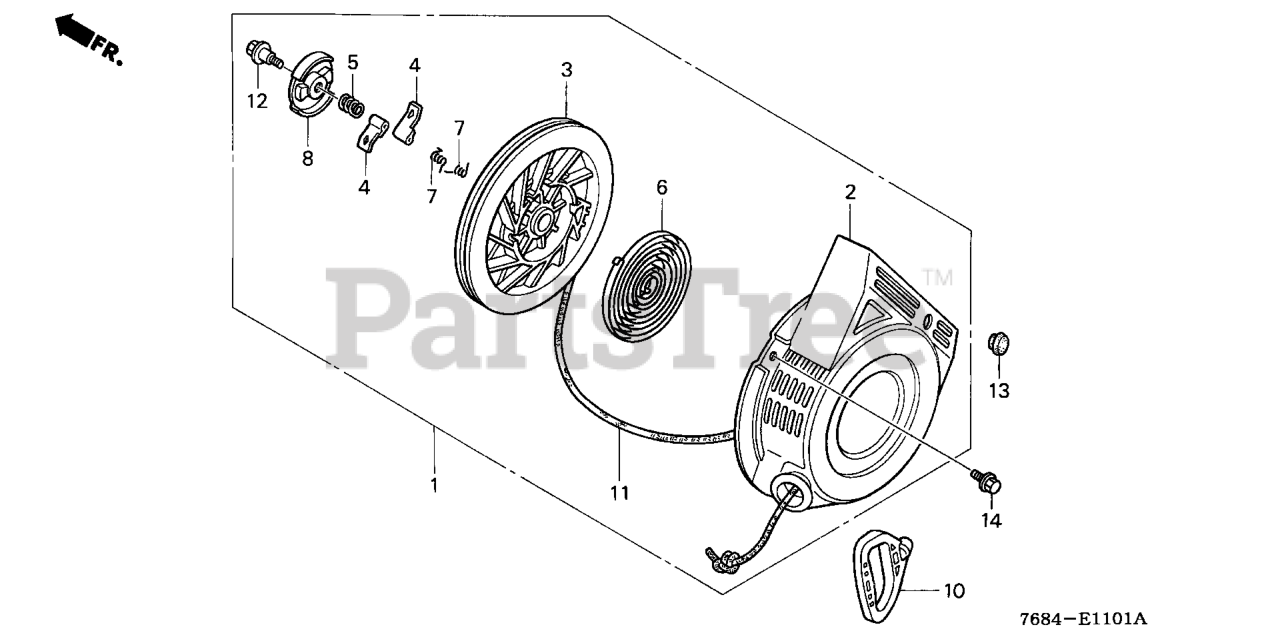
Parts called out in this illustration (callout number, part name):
1	STARTER ASSY., RECOIL *R280* (POWER RED)
2	CASE, RECOIL STARTER *R280* (POWER RED)
3	PULLEY, RECOIL STARTER
4	RATCHET, STARTER
5	SPRING, FRICTION
6	SPRING, STARTER RETURN
7	SPRING, RATCHET
8	RETAINER, SPRING
10	GRIP, STARTER
11	ROPE, RECOIL STARTER (NA USE ALT:08550-ZG921-11)
12	SCREW, CENTER
13	GROMMET B, CONTROL WIRE (16MM)
14	BOLT, FLANGE (6X8)
